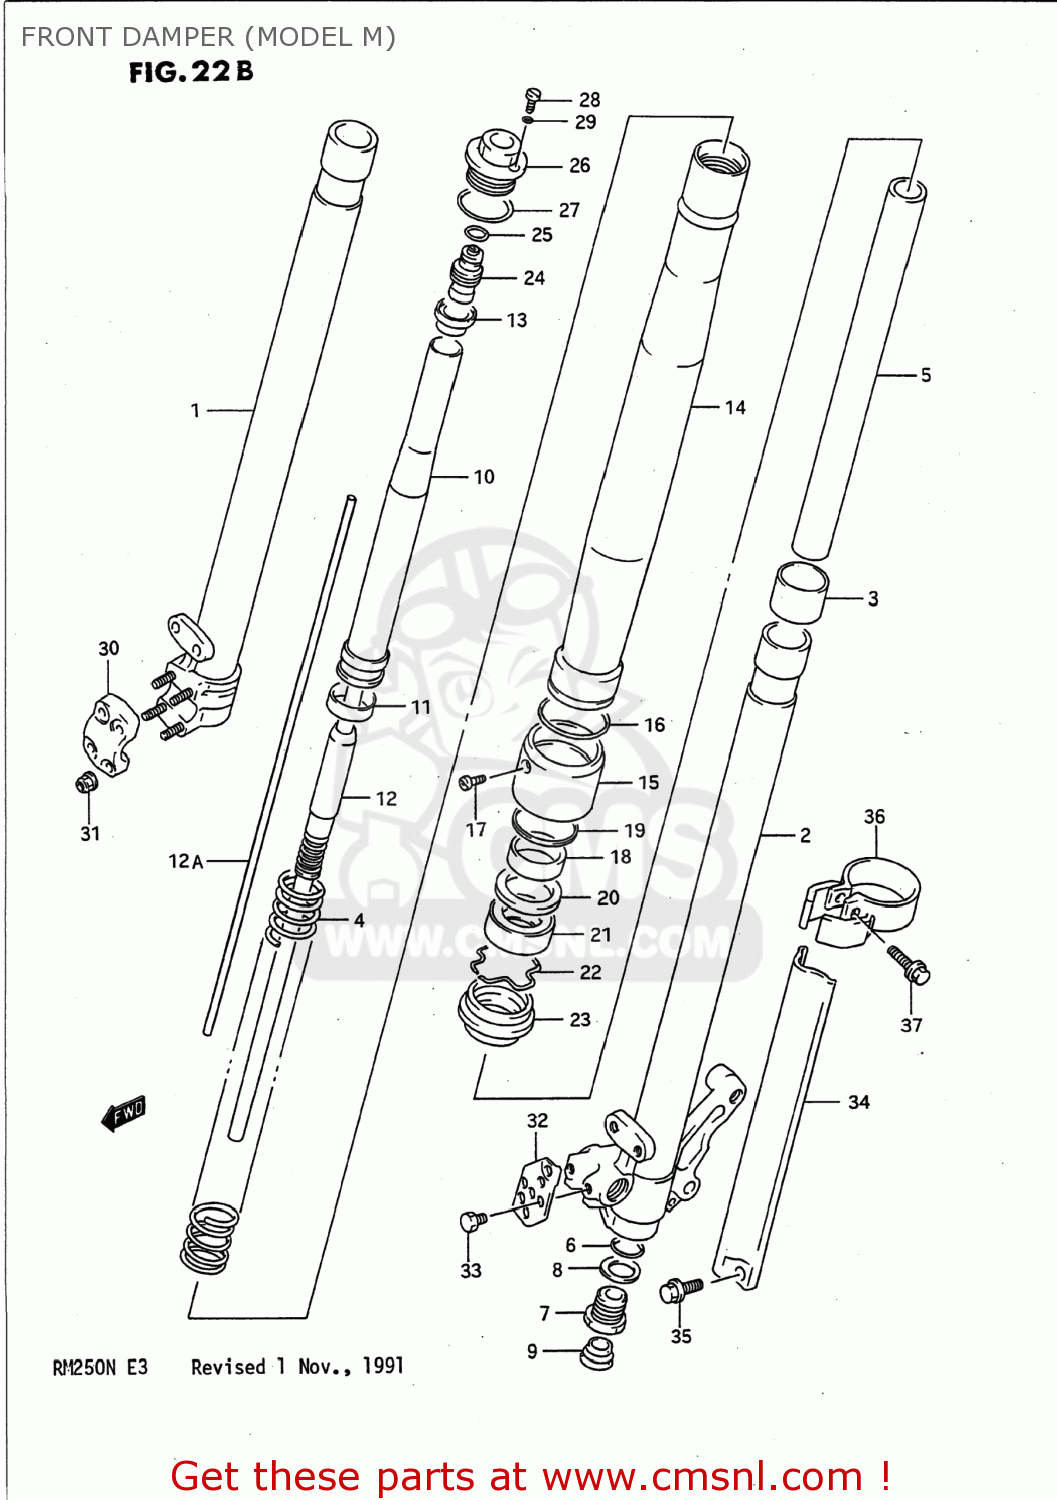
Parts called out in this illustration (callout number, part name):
1	TUBE,INNER,RIGHT
2	TUBE,INNER,LEFT
3	BUSH,SLIDE
4	SPRING,MAIN
5	CYLINDER
6	O-RING
7	BOLT,CTR
8	GASKET (NAS)
9	CAP
10	SPACER,SPRING
11	RING,PISTON
12	ROD ASSEMBLY,PISTON
12A	ROD,PUSH
13	SEAT,SPRING STOPPER
14	TUBE,OUTER
15	CASE,OIL SEAL
16	O RING,CASE
17	SCREW
18	BUSH,GUIDE
19	RING,STOPPER,UPPER
20	SPACER,SEAL
21	OIL SEAL,FRONT FORK
22	RING,OIL SEAL STOPPER
23	SEAL,DUST
24	ADJUSTER,SPRING
25	NUT
26	BOLT,FORK
27	O RING
28	BOLT,PLUG
29	O RING, PLUG
30	HOLDER,AXLE,R
31	NUT
32	GUIDE,HOSE,L
33	BOLT, HOSE GUIDE
34	PROTECTOR,FORK,L
35	BOLT,PROTECTOR(6X10)
36	GUIDE,FORK PROTECTOR,R
37	BOLT,PROTECTOR GUIDE
